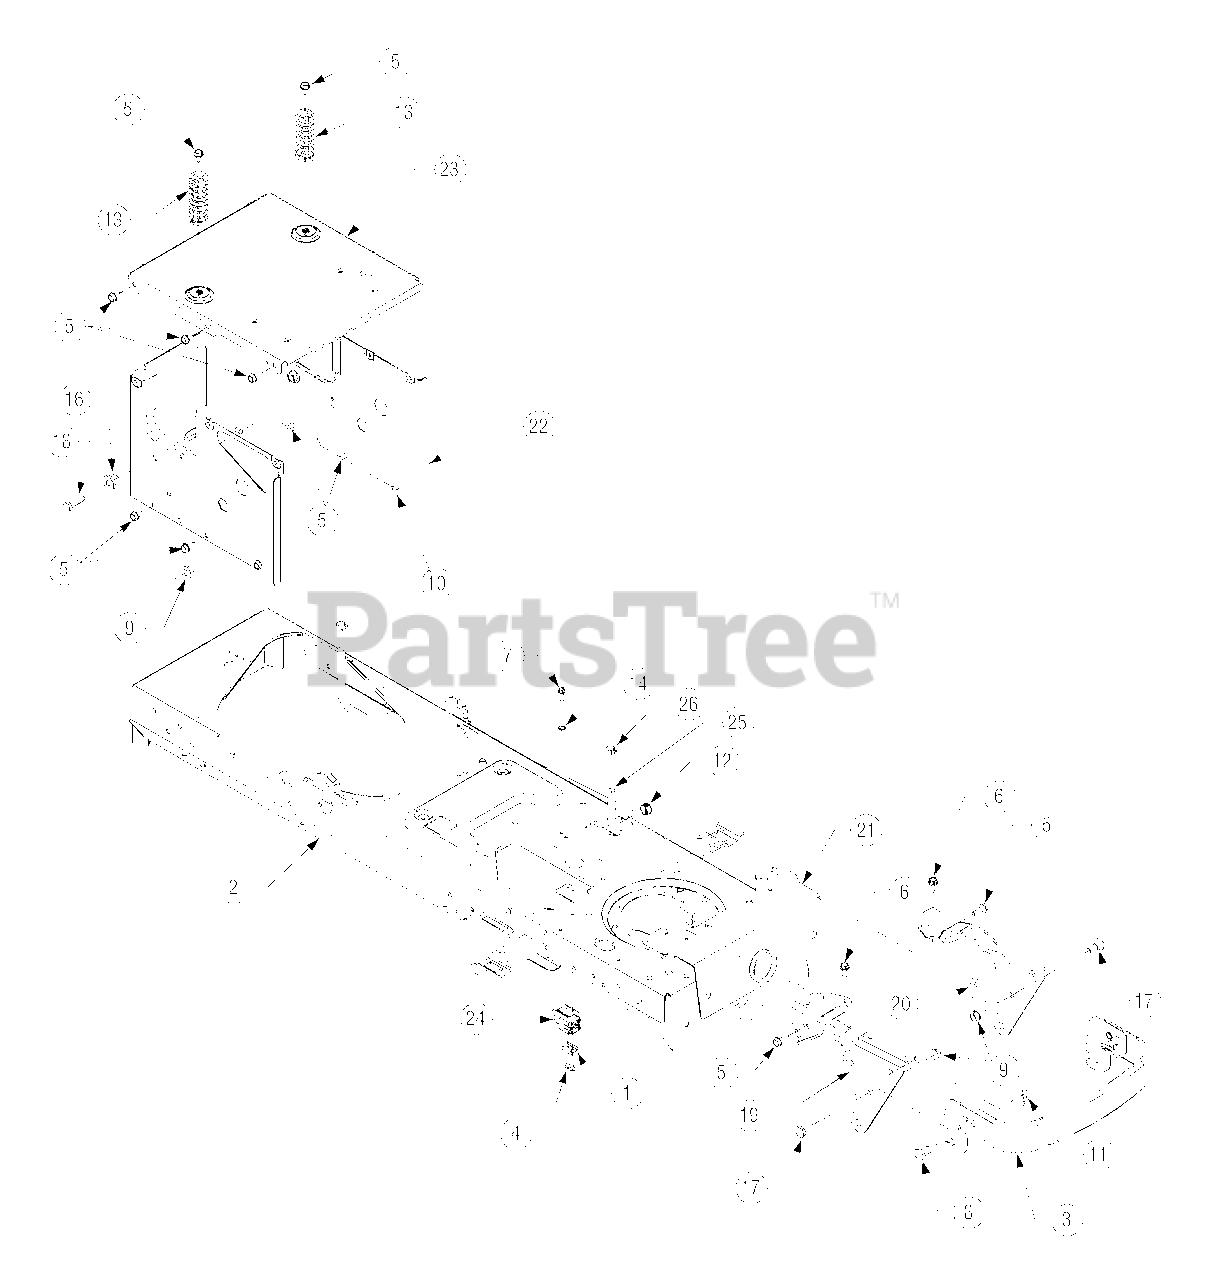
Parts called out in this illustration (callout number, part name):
1	Plate, Switch
5	Screw, Self-tapping, 5/16-18, 0.75
6	Screw, 5/16-18, 0.750
7	Screw, Hex Wash. Hd. Tapp, 1/4-20 x 0.625
8	Pin, Clevis, .50 Dia x .78 Lg
9	Nut, Nylon Lock, 3/8-16
10	Screw, Hex Wash. Tapp, 5/16-18 x .5
11	Pin, Internal Cotter
12	Snap Bushing
13	Spring, Compression, 1.28 OD x 3.125 Lg
14	Washer, Lock, Ext 1/4
16	Shoulder Spacer
17	Shoulder Screw, 3/8-16
18	Hex Screw 3/8-16 x 1.25
25	Fuel Line
26	Clamp, Hose, .490 Dia.
